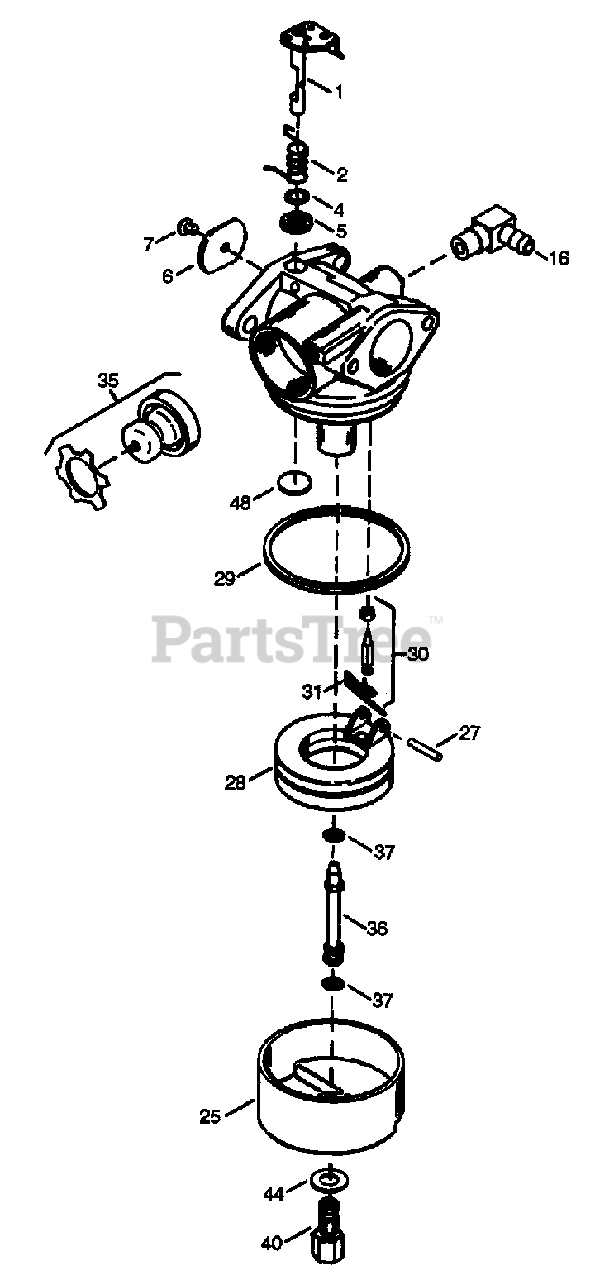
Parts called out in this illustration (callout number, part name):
1	Throttle Shaft & Lever Assembly
2	Throttle Return Spring
4	Dust Seal Washer
5	Dust Seal (Throttle)
6	Throttle Shutter
7	Shutter Screw
16	Fuel Fitting
25	Float Bowl
27	Float Shaft
29	Float Bowl "O" Ring
30	Inlet Needle, Seat, & Clip (Incl. 31)
31	Spring Clip
35	Primer Bulb/Retainer Ring
36	Main Nozzle Tube
37	O-Ring, Main Nozzle Tube
40	High Speed Bowl Nut
44	Bowl Nut Washer
48	Welch Plug, Atmospheric Vent
